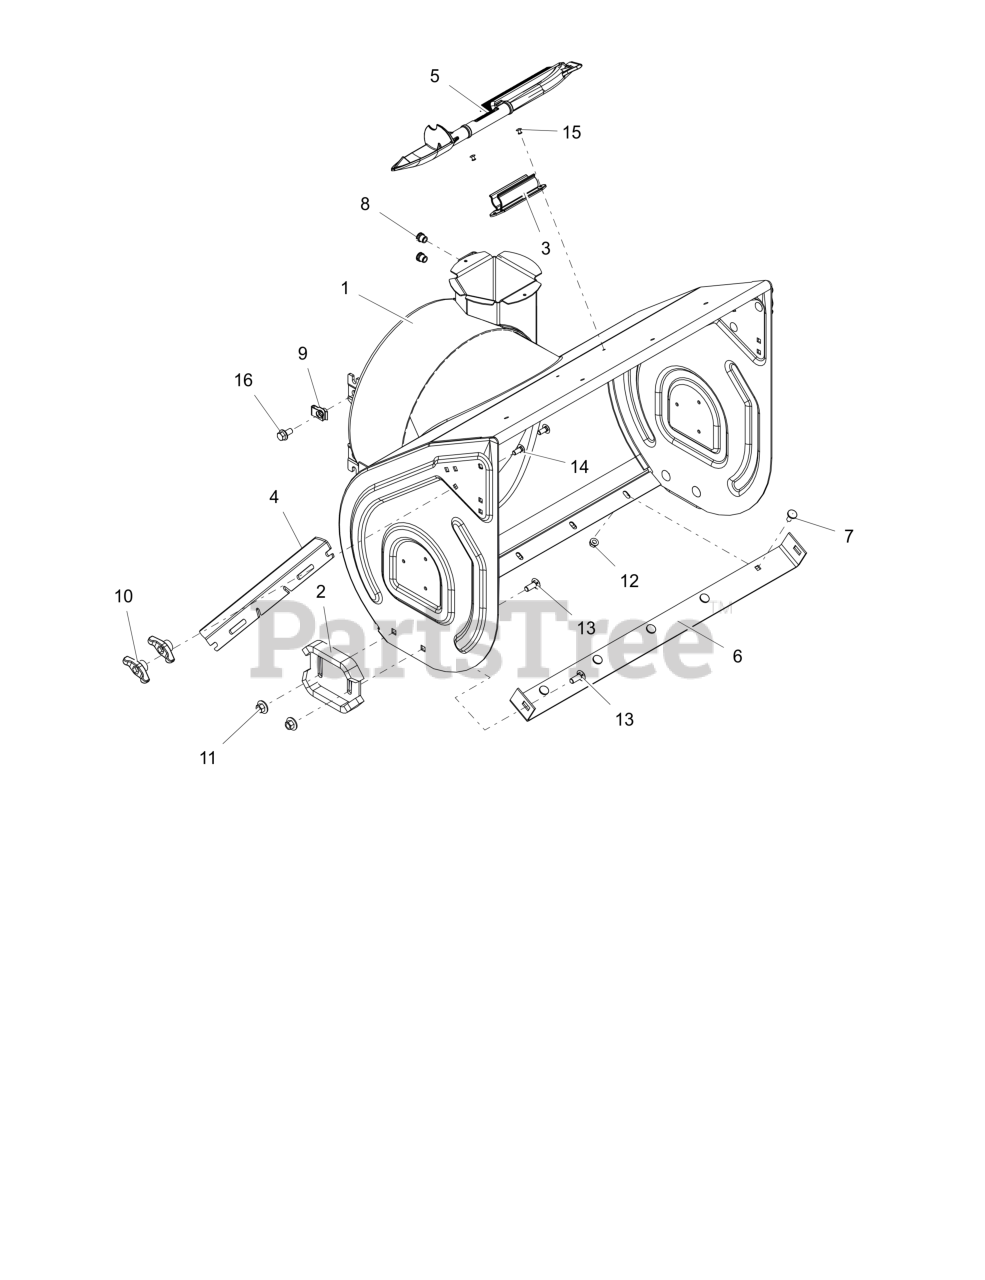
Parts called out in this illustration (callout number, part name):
1	HOUSING, PRO W/DECAL 28"
2	RUNNER, SKID SHOE
3	MOUNT, SNOW CLEAN OUT
4	CUTTER, DRIFT
5	DEVICE, SNOW CLEAN OUT W/BRUSH
6	BLADE, SCRAPER-28"
7	BOLT, MODIFIED HEAD CARRIAGE
8	NUT,THD,INSERT .38-16 ZC120
9	NUT-RTNR .375-16X.37
10	KNOB,WING .31-18 UNC NYL/TALC
11	NUT- CON-LN .375-16 ZC120
12	NUT-LK-TOP-FLG .312-18 GF ZCC
13	BLT,RHSSN .38-16X1.00 G5 ZCC
14	BLT, RHSSN.31-18X.750 G5 ZCC
15	RVT, POP .1875 ZCC
